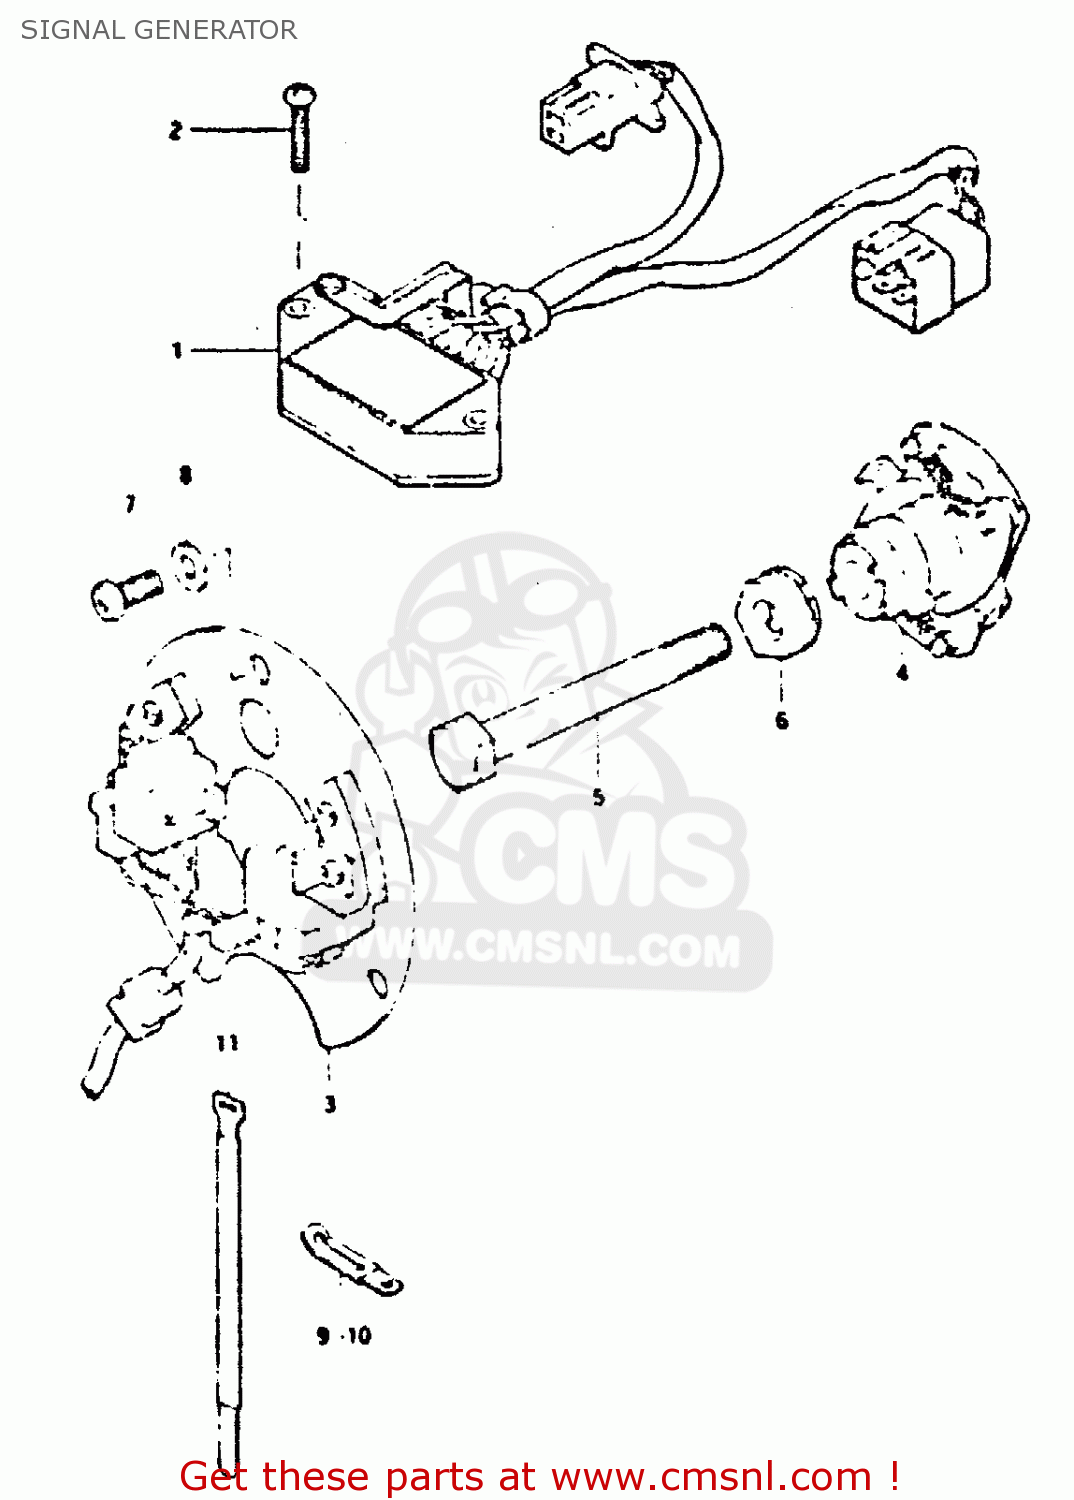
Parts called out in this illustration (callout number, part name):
1	IGNITER UNIT ASSEMBLY
2	SCREW
3	SIGNAL GENERATOR ASSEMBLY
4	GOVERNOR ASSEMBLY
5	BOLT
6	WASHER
7	SCREW(5X12)
8	WASHER
9	CLAMP L:35
10	CLAMP
11	CLAMP
